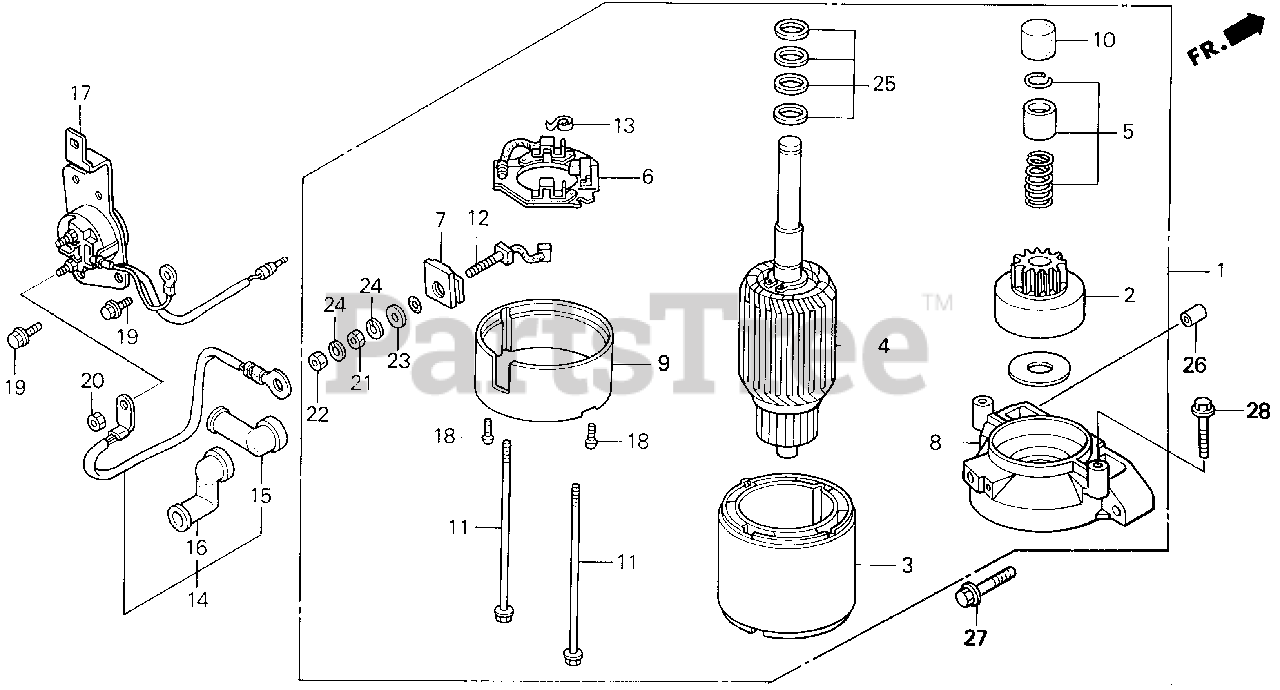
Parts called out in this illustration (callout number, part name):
1	MOTOR ASSY., STARTER
2	CLUTCH, OVERRUNNING
5	STOPPER SET, PINION
6	HOLDER, BRUSH
8	BRACKET, FR.
9	BRACKET, RR.
10	CAP, STOPPER
11	BOLT, THROUGH
13	SPRING, BRUSH
14	WIRE, MAGNETIC SWITCH (120MM)
15	COVER, STARTER MOTOR TERMINAL
16	COVER, MAGNETIC SWITCH TERMINAL
17	SWITCH ASSY., STARTER MAGNETIC
18	SCREW (4MM)
19	BOLT, FLANGE (6X12)
20	NUT, HEX. (6MM)
23	WASHER (1)
24	WASHER (2)
25	WASHER SET, THRUST
26	PIN, DOWEL (10X16)
27	BOLT, FLANGE (6X28)
28	BOLT, FLANGE (8X45)
